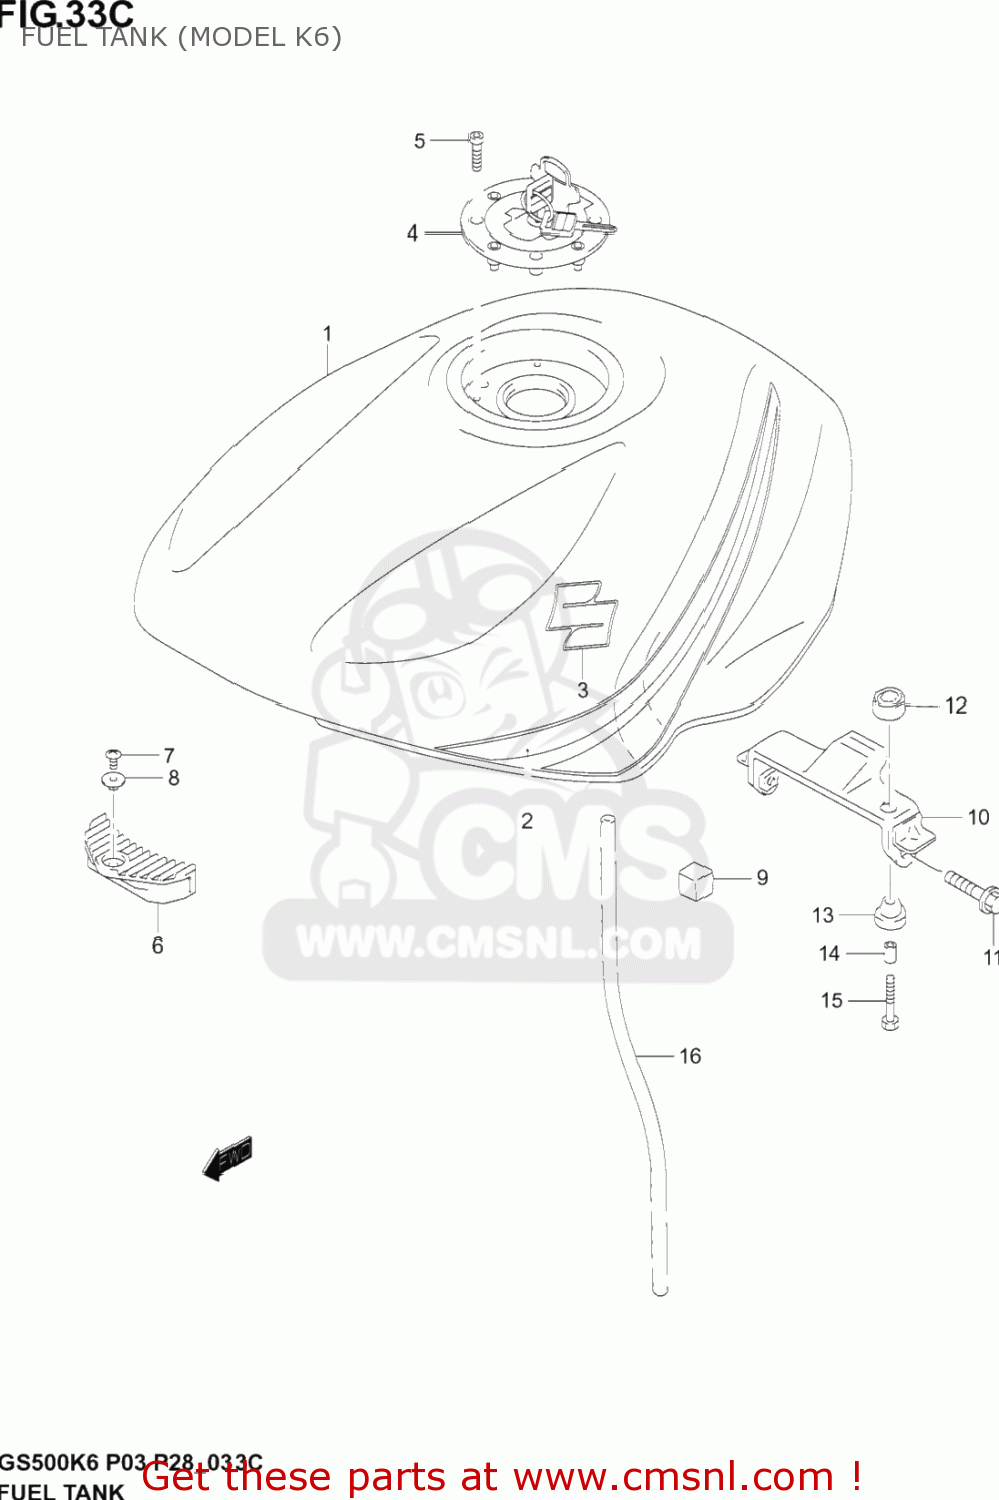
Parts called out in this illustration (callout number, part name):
1	TANK ASSY,FUEL(BLUE)
2	TAPE SET,FUEL TANK
3	EMBLEM,S
4	CAP SET,FUEL TANK
5	BOLT(5X20)
6	CUSHION,FUEL TANK FR
7	SCREW
8	WASHER
9	CUSHION,FUEL TANK SIDE
10	BRACKET, REAR
11	BOLT
12	CUSHION
13	CUSHION
14	SPACER(6.5X9X18)
15	BOLT(6X30)
16	HOSE, DRAIN
